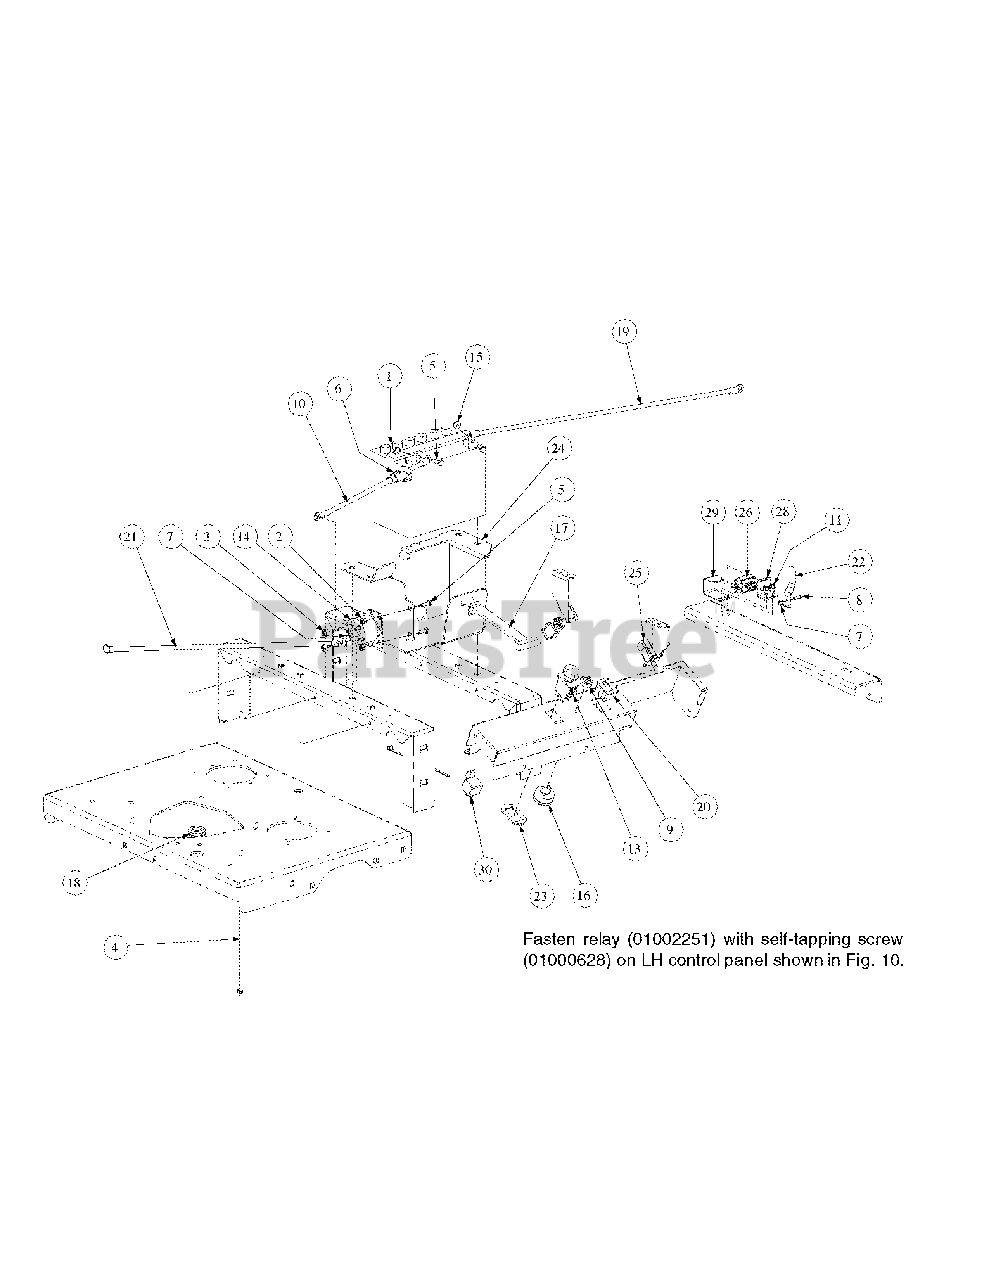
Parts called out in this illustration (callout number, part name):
1	Battery, 12V 225CCA 30 Min
2	Lock Nut w/Nylon Insert
3	Nylock Nut, 5/16-18
4	Tie, Cable, 3/16 x .05 x 7.4"
5	Screw, Hex, Cap, 1/4-20 x .75
6	Boot, 1" OD Rubber Battery-PST, Red
7	Nut, Lock, Nylon Insert, #10-32
8	Screw, Phillips Head, Machine, 10-32 x 5/8
9	Nut, W/Cap, 5/8-32 Ignition
10	Cable, Battery, Red, 15"
11	Screw, TT, 1/4-20, 0.5, Hex Index Washer
13	Switch, Electric, PTO
14	Solenoid Magnetic Switch
15	Hex Flange Lock Nut, 1/4-20
16	Switch, Ignition, 6 Pin
17	Strap, Battery
18	Grommet, .75 ID
19	Cable, Battery Black, 28"
20	Meter, Hour
21	Cable, Battery Red, 32"
22	Spring Retainer
23	Bracket, PTO Switch Retainer
24	Mount Bracket, Battery
25	Switch, Safety N.O./N.C.
26	Switch, Plunger
28	Bracket, Plunger Switch
29	Clamp, Plunger Switch
30	Relay, 12V 40A
